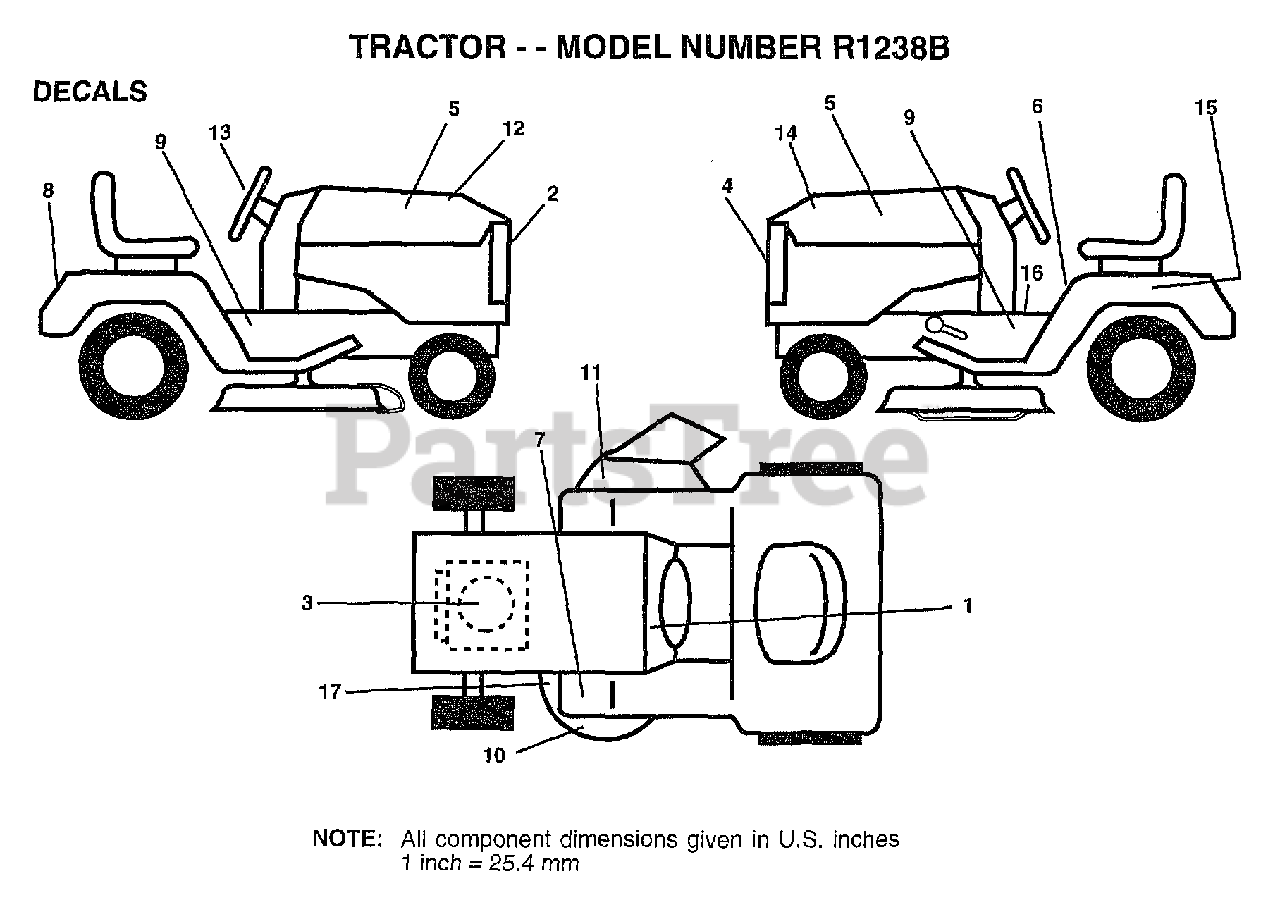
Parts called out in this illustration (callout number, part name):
1	DECAL.INSTR.FRENC
2	GRILL DECAL
3	DECAL, HP ENGINE
5	"DECAL INSERT,HOOD"
6	DECAL.CAUT.ENG/FR
7	DECAL T
8	FENDER DECAL
9	"DECAL.CHASSIS.38"""
11	"DECAL, WARNING"
12	DECAL HOOD RH RLY
13	"DECAL,STR WHL"
14	DECAL HOOD LH RLY
15	DECAL.BATRY.3-3908
16	DECAL BRAK PARK
17	DECAL
